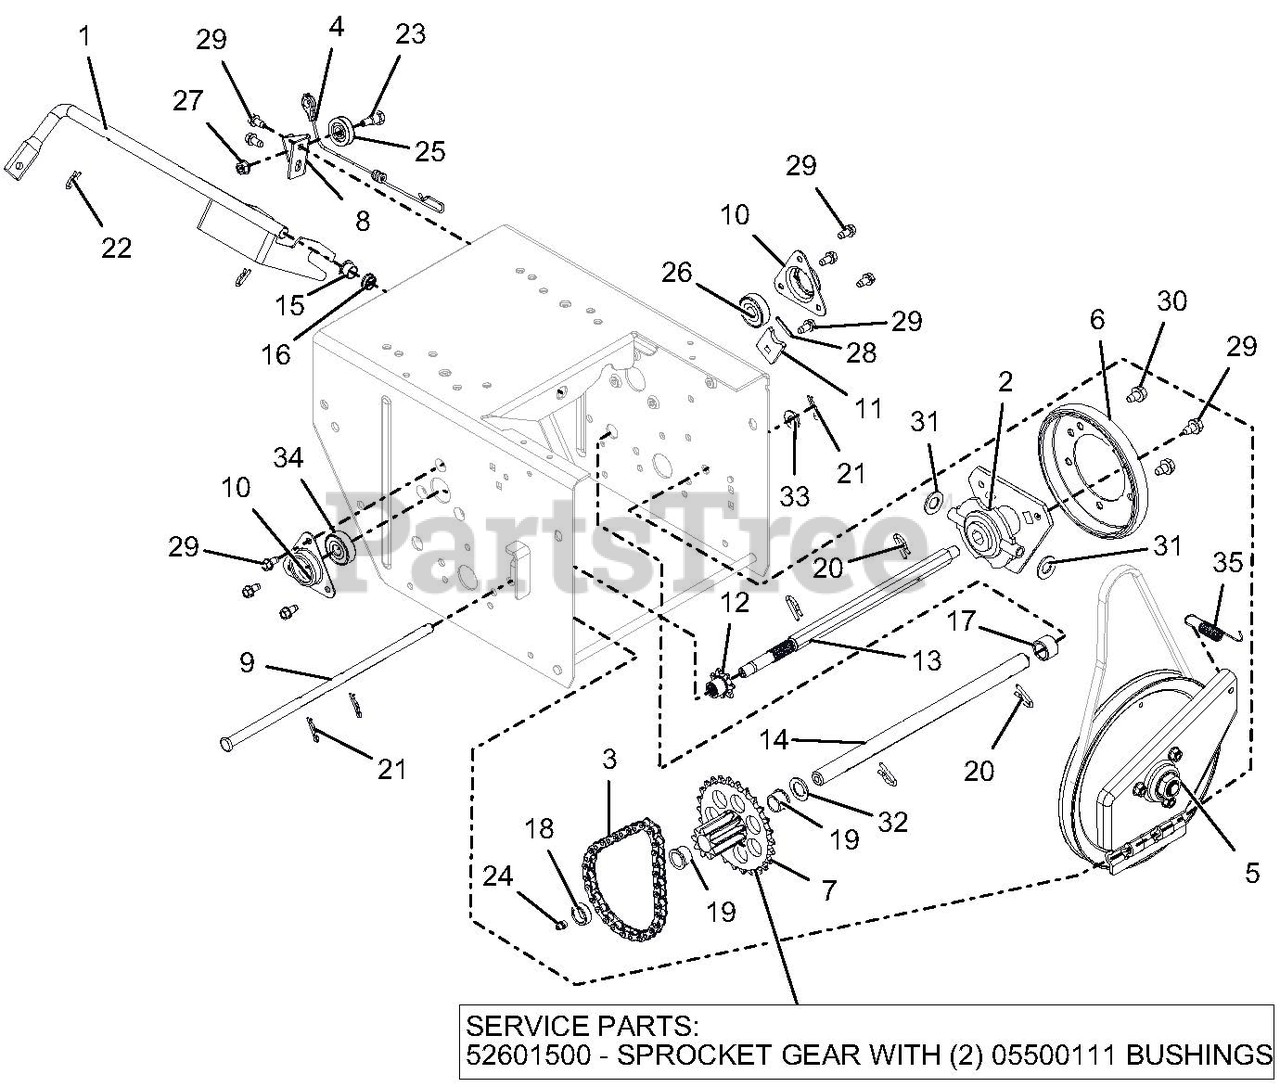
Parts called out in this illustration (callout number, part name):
1	ARM, SHIFT-WELDMENT
2	CARRIER, DRIVE DISK
3	CHAIN - #41, 32 PITCHES
4	CABLE, LOWER TRACTION,SS & PRO
5	PLATE, SWING ASSEMBLY-DEEP
6	FRICTION, DISC
7	PINION & SPROCKET
7	PINION & SPROCKET W/BUSHINGS
7	BSHG-FLG .625X.750X.500X.875
8	BRACKET, CABLE PULLEY
9	PIN, PIVOT
10	FLANGE, BEARING
11	TAB, ANTI ROTATION
12	SPROCKET, PINION 7T W/SPLINE
13	SHAFT, HEX-W/SPLINE TRACK
14	SHAFT, PINION - HARDENED
15	BUSHING, POLYLINER-.50 SPLIT
16	BUSHING, POLYLINER-.50 SNAPIN
17	SPACER, .635X.880X.611
18	BSHG-SLV, .635X.880X.305
19	BSHG-FLG .625X.750X.500X.875
20	PIN, SPRING CLIP
21	PIN-HAIR, ENDRIES #25 YWZC
22	CLIP, SPRING
23	BOLT, SHLDR-.375X.375X.25-20
24	ZERK,FITTING .25X.125 DRIVE IN
25	PULLEY, CABLE
26	BRG-BALL .669X1.575X.47(6203Y)
27	@NUT-LK-TOP-FLG .31-18 YWZC
28	PIN-ROLL .125X1.00
29	SCR-TAP .25-20X.50 HWH TR YWZ
30	@SCR-TAP .31-18X.50 HWH TR YWZ
31	WSHR-FL-STL .505X1.00X.062YWZC
32	WSHR-FL-STL .406X1.00X.188 YWZ
33	@WSHR-FL-STL.406X.812X.065 YWZ
34	BRG-BALL .437X1.375X.437
35	SG-TENS .048X.50X2.8
